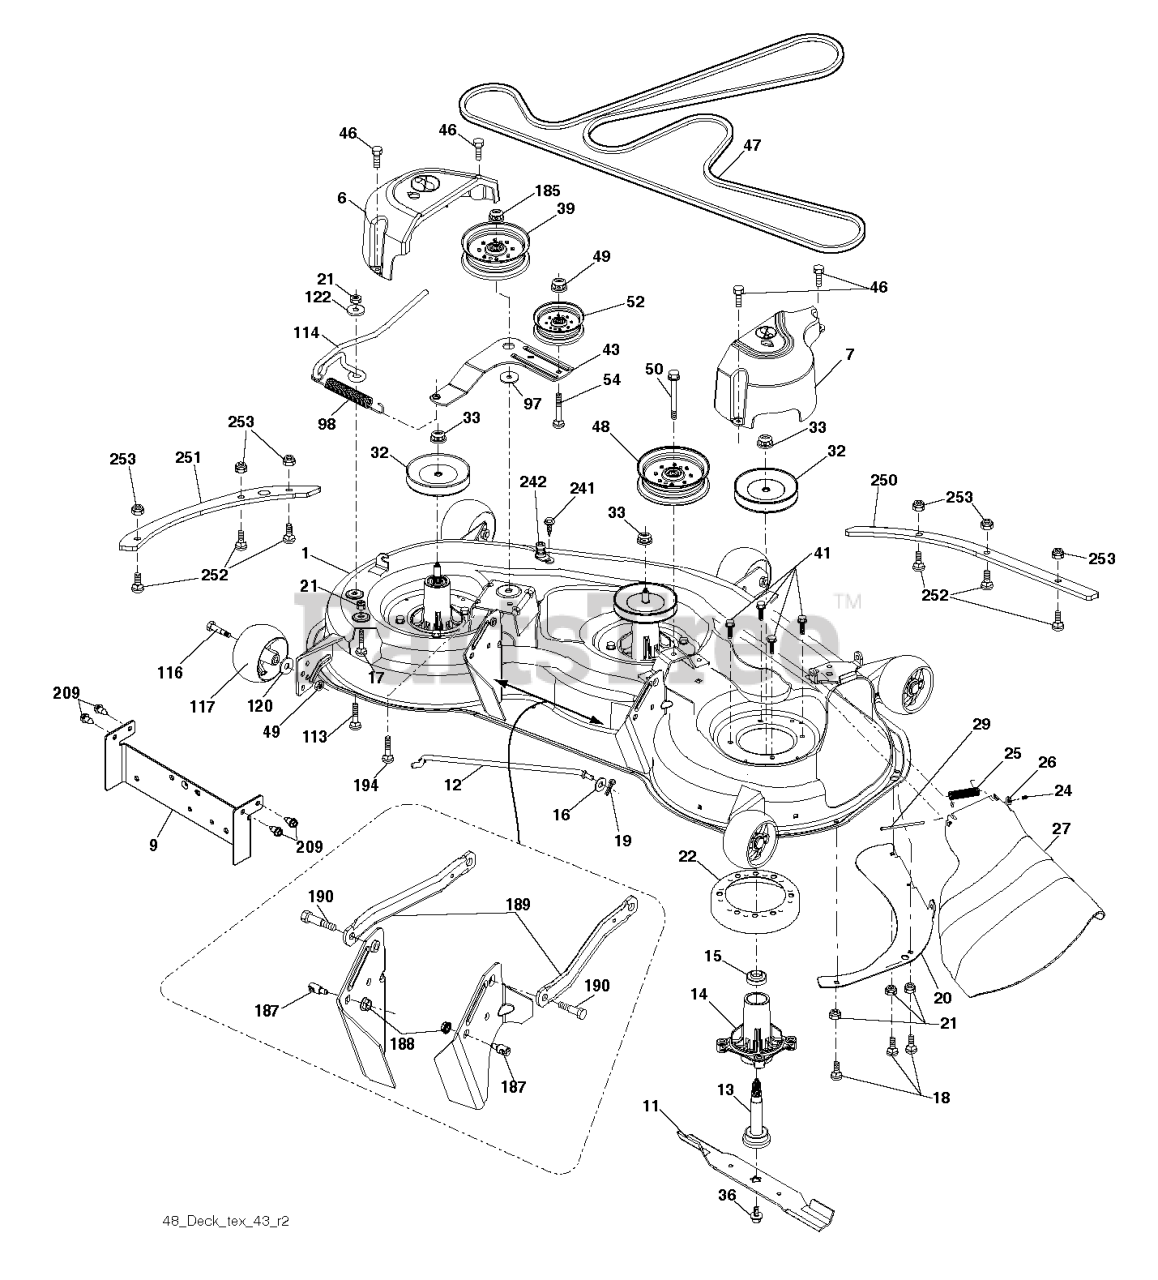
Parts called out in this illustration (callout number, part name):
1	DECK.WLDMT.W/TUBES.48".OR.RP
6	COVER.MANDREL.LH.48"(2 2)
7	COVER.RH.MANDREL
9	TORQUE.STRAP.PNT.BLACK
11	48" HI-LIFT BLADE
12	ROD.ANTI.SWAY.48/54"K4
13	SHAFT ASM MANDREL
14	RP.HOUSING.MANDREL.4PT.
16	WASHER
17	BOLT.CARR.5/16-18X5/8.SHORT
18	BOLT
19	PIN.COTTER.5/16.BOW TI
20	BAFFLE, VORTEX MWR
21	LOCKNUT
22	STRIPPER.MANDREL.ROUND.BLACK
24	CAP-SLEEVE LT
25	SPRING, TORSION
26	NUT PUSH M
27	DEFLECTOR SUBS TO 532 180655
29	ROD.HINGE
32	PULLEY MANDREL
33	NUT.FLANGE.LOCK.TOP
36	SCREW.SEMS.7/16-20X1.HEX.HEAD
39	RB PULLEY.IDLER.4.50/HUB SPEC
41	BOLT.HEX.WASHR.HED.313-18X1.19
43	ARM.IDLER
46	SCREW.1/4-20X5/8
47	BELT.DRIVE.DECK
48	PULLEY.IDLER.2006
49	NUT LOCK FLG 3/8-16 UNC
50	SCREW TT 3/8-16X2-1/4 UNC
52	PULLEY.IDLER.48"PRIMARY
54	BOLT.3/8-16X1.50
98	SPRING, DECK DRIVE
113	BOLT CRT
114	ROD.TENSION.RELIEF.TEX (2 2)
116	BOLT.SHOULDER.3/8-16X3-5/8.
117	RP WHEEL. GUAGE RALLY
120	WASHER
122	BUSHING.RELIEF.TENSION
185	NUT.LOCK.FLANGE.7/16
187	STUD.FASTNER.W/ANTI-ROTATE
188	NUT LOCK HEX FLANGE 5/16-18
189	ARM.SUSPENSION.MOWER
190	BOLT.SHOULDER
194	BOLT.HEX.WASHER.HEAD.7/16-24X
209	SCREW
241	SCREW.TT.#10-32X.5.3/8.FLANGE
242	PORT.WASHOUT
250	PLATE.REIN.FRNT.BOLTON.48X431
251	PLATE.REIN.SIDE.BOLT.ON.48X431
252	RHSNB, 1/4-20 X 1, GR5
253	NUT T
